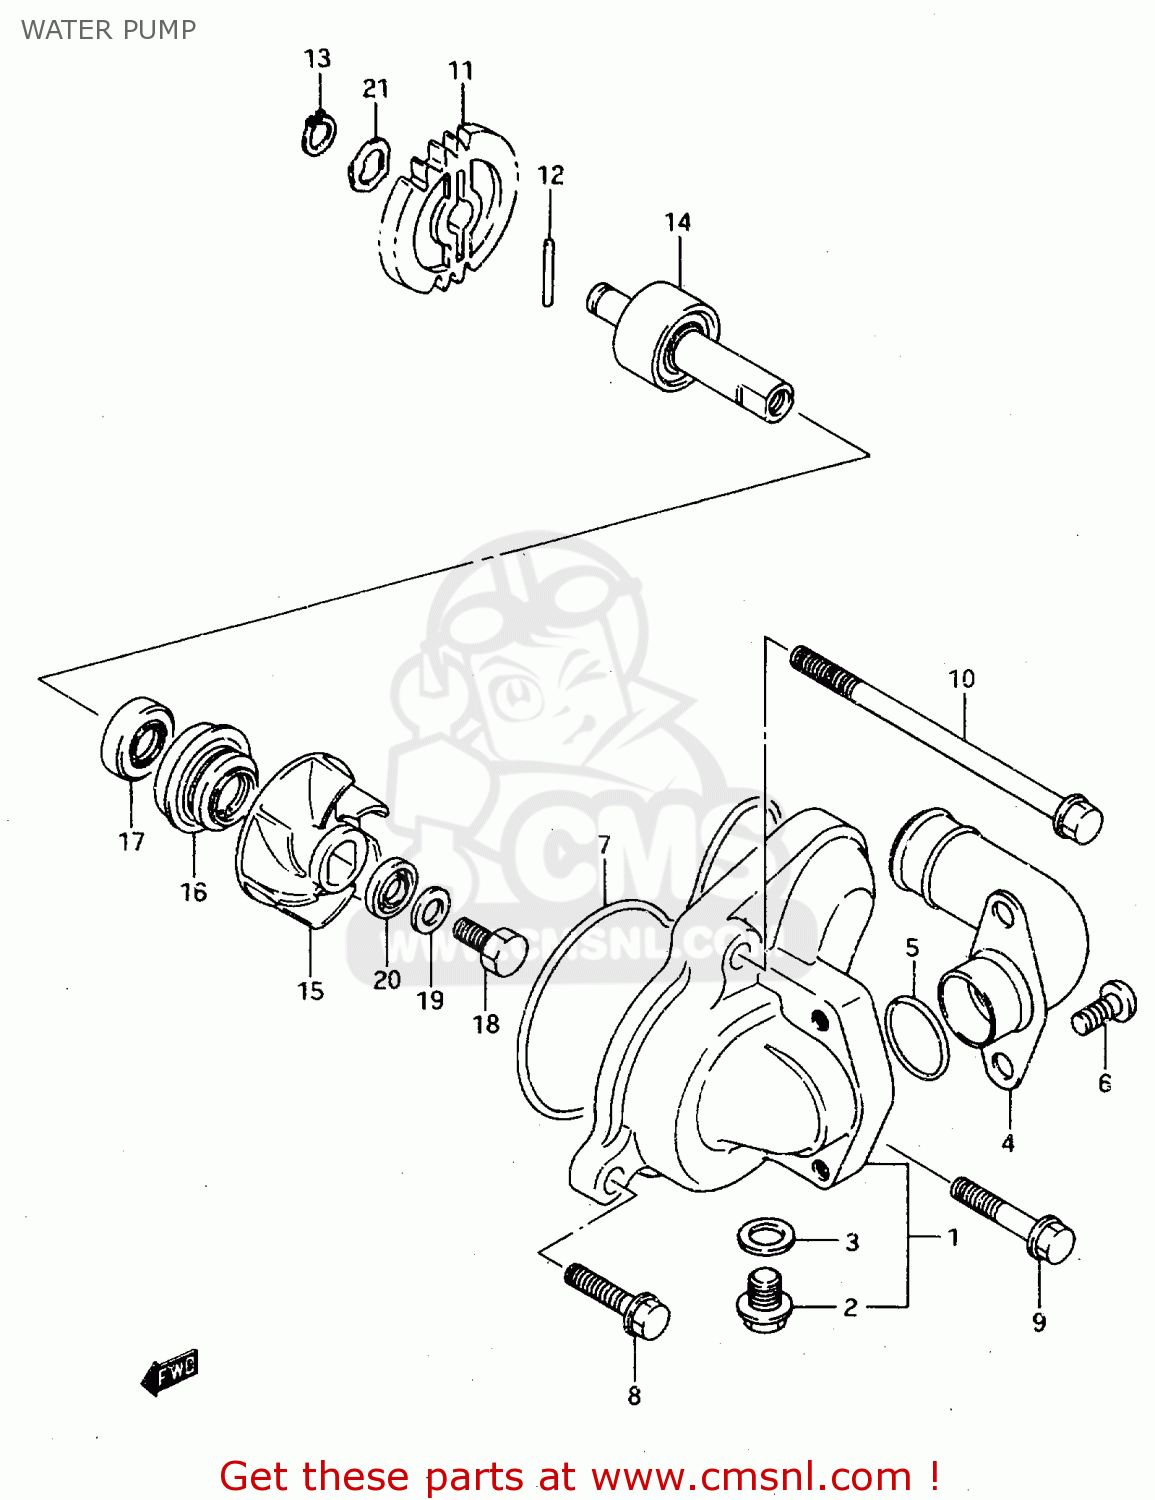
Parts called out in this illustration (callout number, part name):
1	CASE,WATER PUMP
2	BOLT,DRAIN
3	GASKET 8.2X14X1 (NAS)
4	CONNECTOR,WATER INLET
5	O RING(D:1.9,ID:18.8)
6	BOLT
7	O RING,WATER PUMP CASE
8	BOLT
9	BOLT
10	BOLT
11	GEAR,WATER PUMP DRIVEN
12	PIN(2.5X19.8)
13	CIRCLIP,10MM
14	SHAFT,WATER PUMP
15	IMPELLER,WATER PUMP
16	SEAL,MECHANICAL
17	SEAL,OIL(10X20X5)
18	BOLT(6X13)
19	WASHER
20	GASKET(6X15X2.2) (NAS)
21	WASHER
